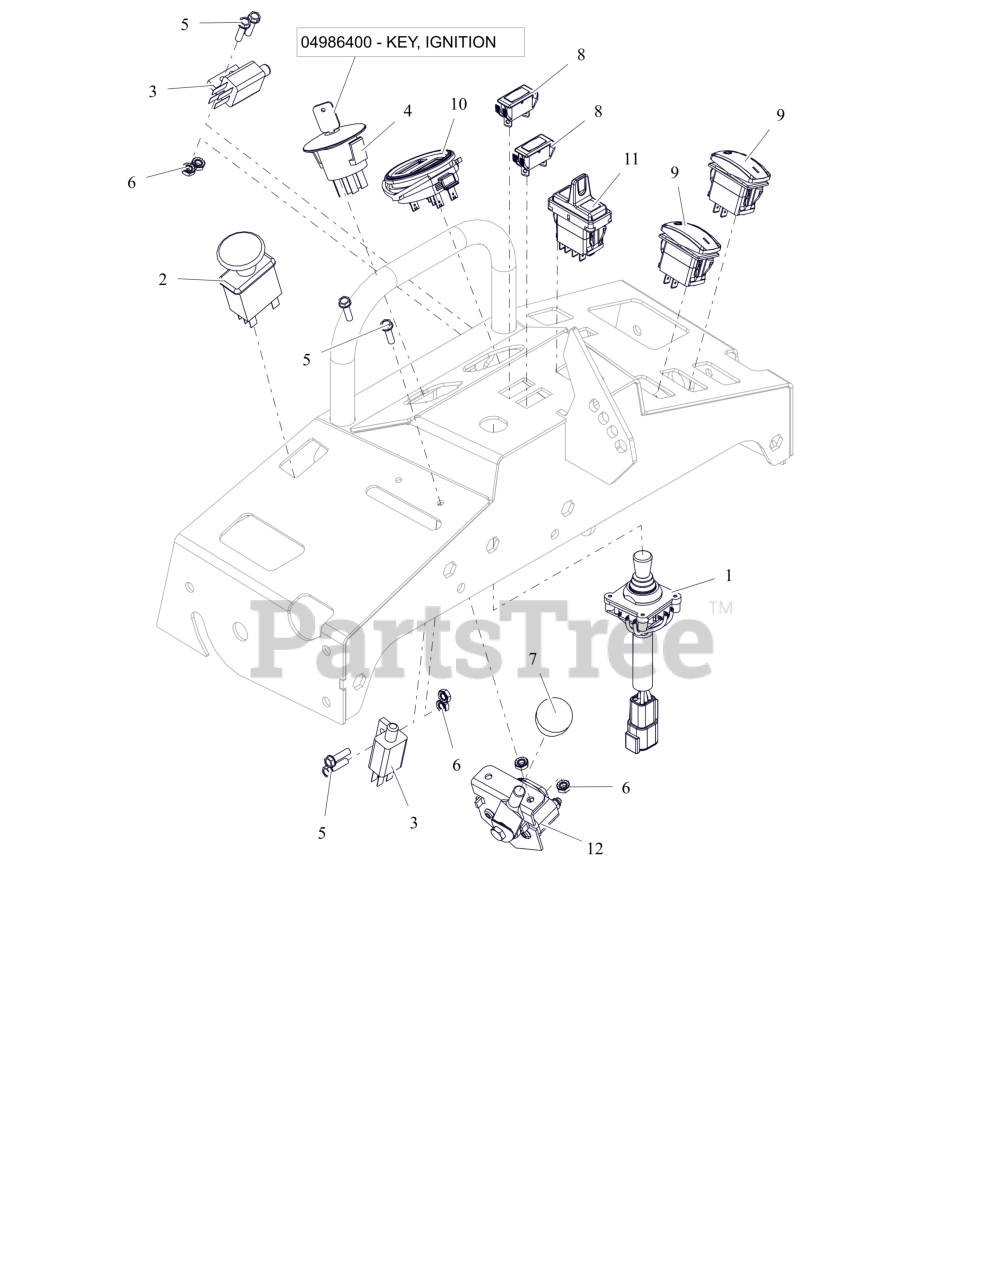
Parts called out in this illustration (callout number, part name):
1	ASSY- JOYSTICK (NO)
2	SWITCH, CLUTCH
3	SWITCH- DOUBLE POLE N.O./N.O.
4	KEYSWITCH-IGNITION 4 POS
4	KEY, IGNITION
5	BLT, HWH #10-24X.75 ZCC
6	NUT, KEPS #10-24 ZCC
7	KNOB-CONTROL-BLACK .38-16X.50
8	LIGHT,INDICATOR
9	SWITCH, ROCKER - BLANK ON/OFF
10	METER, DUAL
11	SWITCH- PADDLE ROCKER
12	CONTROL- ELECTRIC THROTTLE
